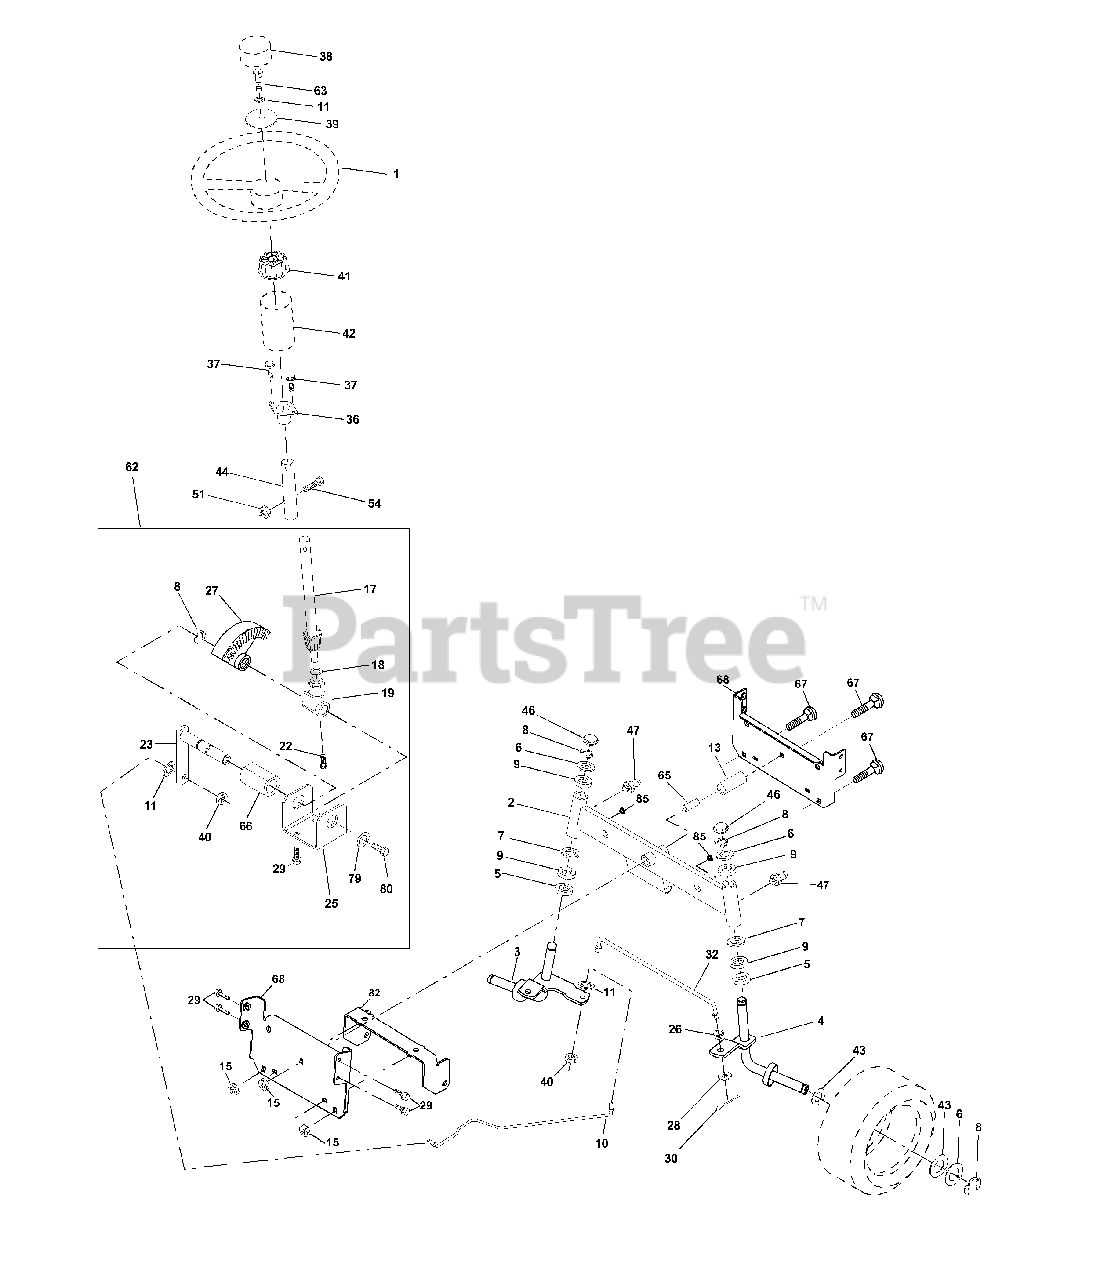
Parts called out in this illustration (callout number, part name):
1	Wheel Steering Auto Black
2	Axle Asm Front
3	Spindle Asm Lh
4	Spindle Asm Rh
5	Bearing Race Thrust Harden
6	Washer 25/32 X 1 5/8 X 16ga
7	Washer 27/32 X 1 1/4 X 16 Ga
8	Ring Klip #t5304-75
9	Bearing Col Strg Blk
10	Link Drag Extended
11	Lockwasher
13	Spacer Bearing Axle Front
15	Hex Flange Lock
17	Shaft Asm Strg 5/8 X 15 19 Lt
18	Washer Thrust 515x 750x 033
19	Support Shaft
22	Screw Hex Wsh Hd Torx
23	Shaft Asm Pittman
25	Bracket Steering
26	Bushing Rod Tie Blk Lt
27	Gear Sector
28	Washer 13/32 X 7/8 X 16ga
29	Screw 3/8-16x3/4
30	Pin
32	Rod Tie Wire Form 19 75 Mech
36	Bushing Strg 5/8 Id Dash
37	Screw TT #10-32 x 5 x 3/8 Flange
38	Insert Cap Strg
39	Washer 13/32 x 2-3/8 x 12Ga
40	Locknut Center
41	Adaptor Wheel Strg 640/ 635id
42	Boot Dash Steering
43	Washer 25/32 X 1 1/4 X 16 Ga
44	Extension Steering Non-Adjust
46	Cap Spindle Fr Top Blk
47	Fitting Grease
51	Nut Lock Hex W/Ins.
54	Bolt Fin Hex 5/16-18 Unc P
62	Kit Steering Assembly Service
63	Bolt Fin Hex 3/8-16unc x Gr. 5
65	Spacer Brace Axle
66	Bearing Arm Pittman
67	Bolt Rdhd Sq 3/8-16 Unc x 2-3/4
68	Brace Axle
79	Washer 13/32 x 1-1/4 x 12 Ga
80	Bolt Hex Nylon 3/8-16 x 3/4
82	Bracket Susp Chassis Front
85	Fastener Christmas Tree
